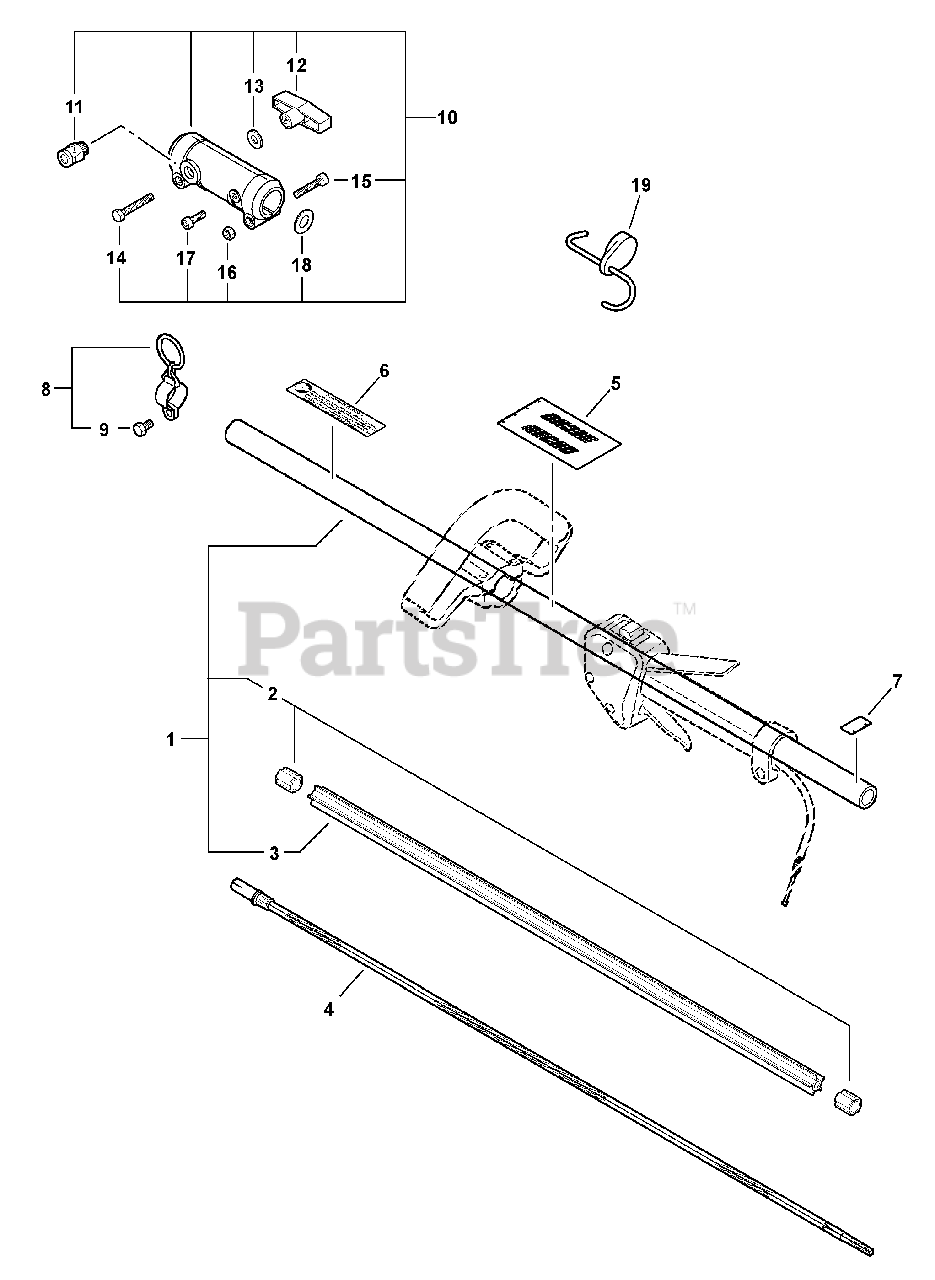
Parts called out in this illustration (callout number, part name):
1	Main Pipe Asy
3	Liner, Flexible
4	Driveshaft - Flexible
5	Label - Handle Location
6	Label - Caution - Spanish
7	Label - Pipe Location
8	Harness Ring Asy
9	Bolt 5x12
10	Coupler Asy
11	Latch Asy
12	Knob
14	Bolt 6x40
15	Screw 6x25
17	Screw 6x10
19	Pas Attachment Hanger
